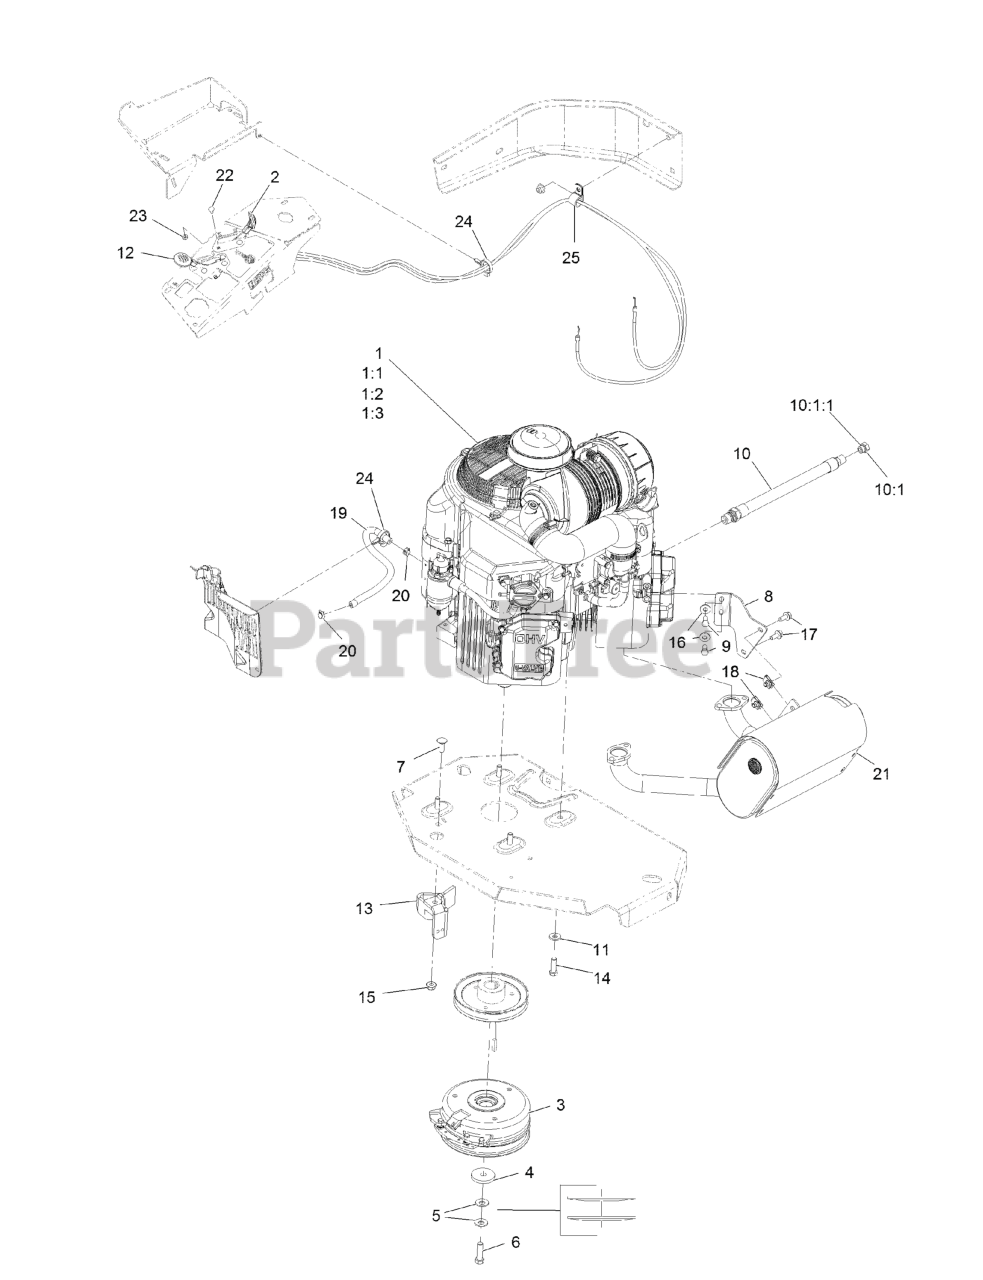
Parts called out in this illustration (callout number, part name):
1:1	Kawasaki 49065-7007 Engine Oil Filter
1:2	Kawasaki 11013-7044 Engine Air Filter
1:3	Kawasaki 11013-7045 Safety Filter
2	CONTROL, CHOKE
3	CLUTCH KIT
4	WASHER-CLUTCH
5	WASHER-SPRING
6	SCREW-HH 7/16-20 X 1 1/2 W/LOCTITE
7	SCREW-CARR
8	BRACKET-MUFFLER
9	SCREW-HH
10	ENGINE OIL DRAIN HOSE ASM
10:1	PLUG-HH
10:1:1	O-RING
11	WASHER-BELLEVILLE
12	ASM,THROTTLE CABLE
13	CLUTCH-ANCHOR
14	SCREW-HH
15	NUT-HF, NI
16	WASHER-SPRING
17	SCREW-HHF
19	HOSE-FUEL
20	CLAMP-HOSE
21	MUFFLER
22	BOLT-CARR
23	NUT-LOCK, NI
24	CLAMP-HOSE
25	CLIP-LOOM
